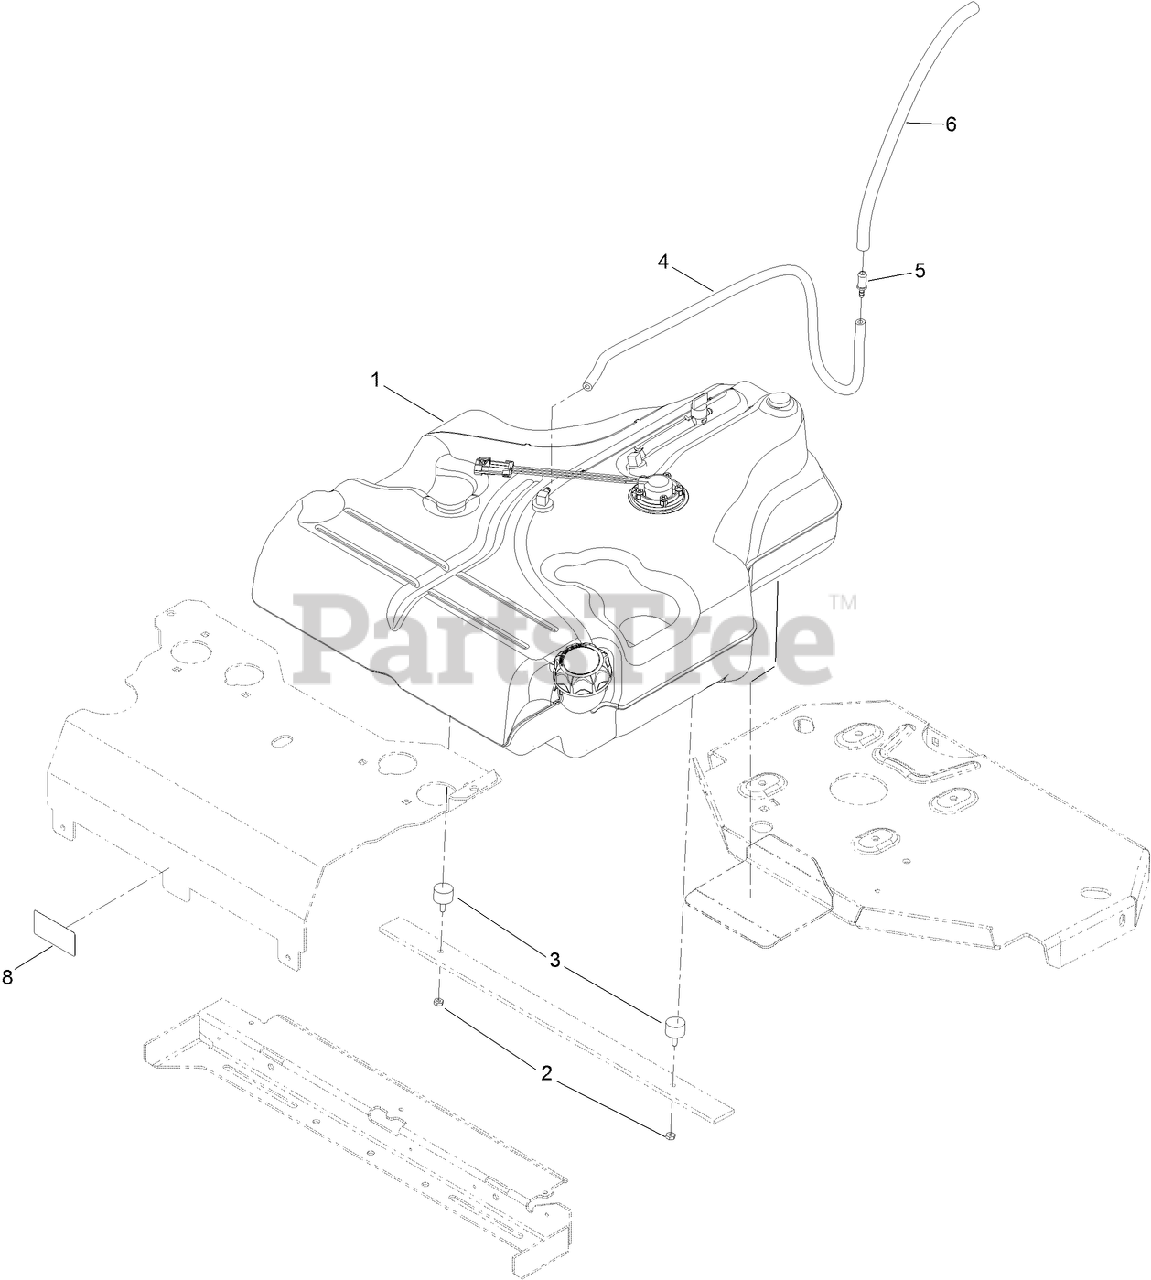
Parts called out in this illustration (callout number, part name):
1	FUEL TANK ASM
2	NUT-JAM
3	BUMPER
4	HOSE-FUEL
5	FITTING-STRAIGHT
6	HOSE-FUEL
8	DECAL-EFI
